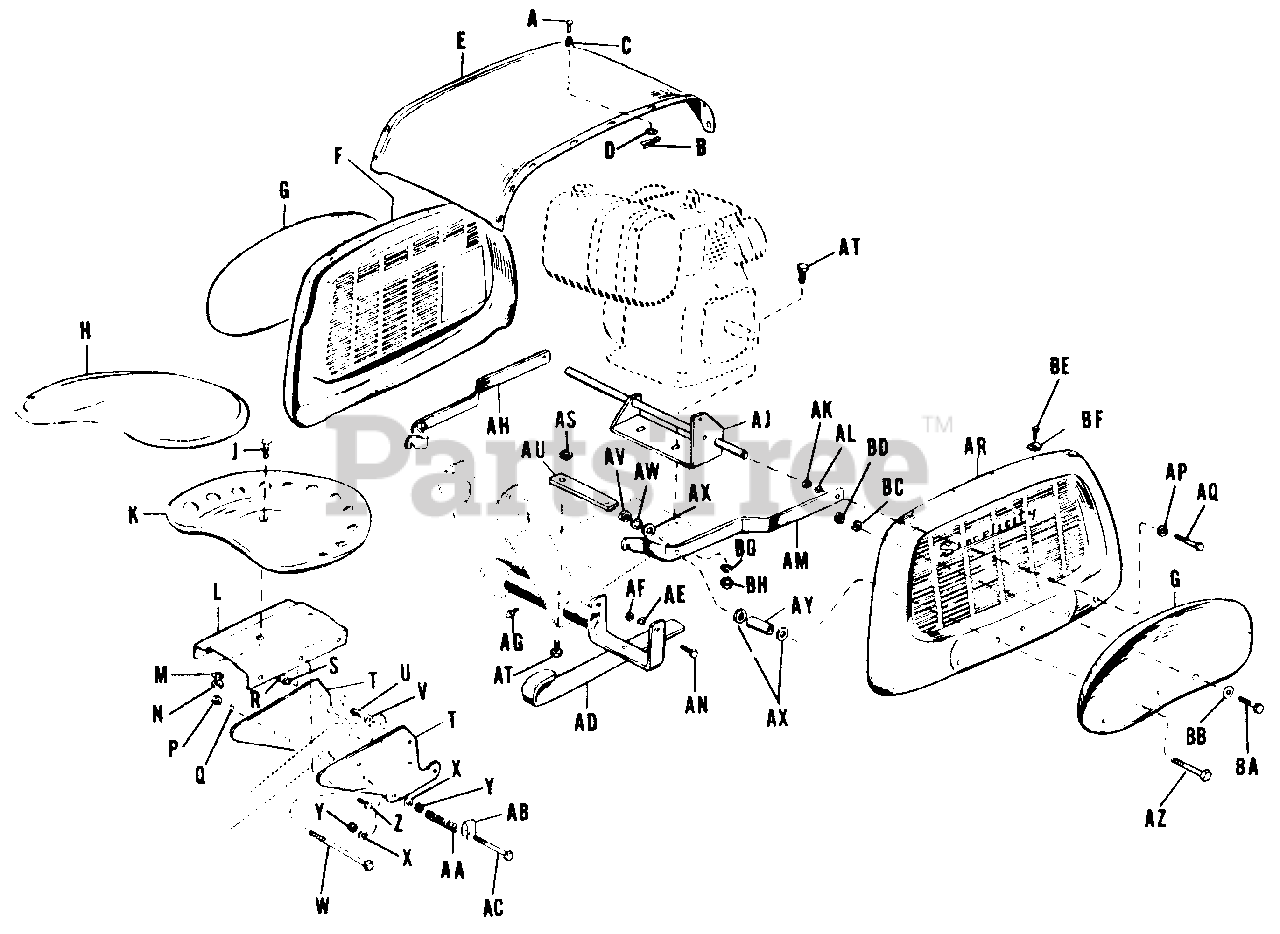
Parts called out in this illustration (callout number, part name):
A	Pin, Engine Stop
B	Pin, Cotter 3/32 x 1
D	Washer, Plain 3/16
E	Panel, Top
F	Panel, Side, RH
J	Bolt Carriage 1/2-13 x 1 1/4"
L	Bracket Seat
M	Washer 1/2"
N	Nut, Full Hex, 1/2-13
P	Nut, Full Hex, 3/8-16
Q	Washer, Lock 3/8"
R	Nut, Full Hex 3/8-16
S	Washer, Lock 3/8"
T	Plate, Side
U	Screw, Hex Cap 7/16-20 x 3/8"
V	Washer, Lack, 7/16"
W	Bolt, Sq. Hd. Mach. 3/8-16 x 6"
X	Washer, Plain 3/8"
Y	Nut, Full Hex, 3/8-24
Z	Screw, Hex. Cap 3/8-16 x 1"
AA	Spring, Latch
AC	Screw, Hex. Cap 3/8-24 x 4 3/4"
AD	Draw Bar Assembly
AE	Washer, Lock, 3/8"
AF	Nut, Full Hex, 3/8-16
AG	Grease Fitting No. 1637
AH	Latch, Hood, R.H
AJ	Bracket, Pivot Assembly
AK	Nut, Full Hex, 3/8-16
AL	Washer, Lock, 3/8"
AM	Latch, Hood, L.H.
AN	Screw, Hex Cap, 3/8-16 x 1
AP	Washer, Plain, 3/8"
AQ	Screw, Hex Cap, 3/8-16 x 1 1/2"
AR	Panel, Side, L.H.
AS	Nut, Sq., 3/8-16
AT	Screw, Hex Cap, 3/8-16 x 1 1/4"
AU	Spacer, Engine
AV	Nut, Full Hex, 3/8-16
AW	Washer, Lock, 3/8"
AX	Washer, Plain, 3/8"
AY	Spacer, Latch
AZ	Screw, Hex Cap, 3/8-16 x 2"
BA	Screw, Hex Cap, 3/8-16 x 5/8
BB	Washer Plain, 3/8"
BC	Washers Lock, 3/8"
BD	Nut, Full Hex, 3/8-16
BE	Screw, No. 10 x 1/2"
BF	Nut, Type "E"
BG	Washer, Lock, 3/8"
BH	Nut, Full Hex, 3/8-16
